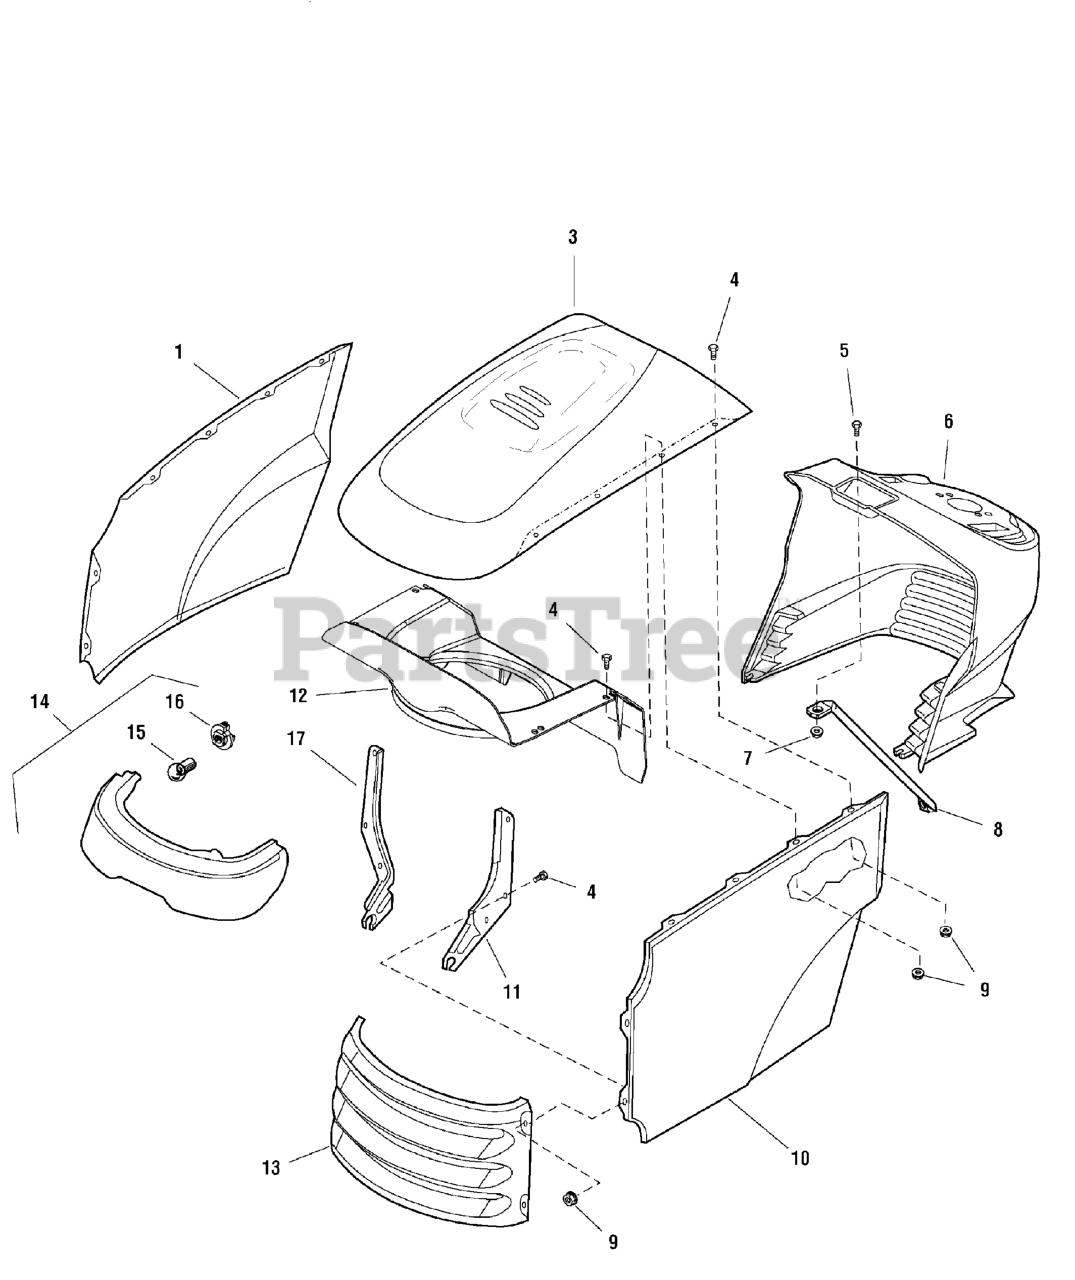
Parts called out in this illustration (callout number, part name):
1	PANEL, RH Side
3	HOOD, with Louvers
4	CAPSCREW, Hex Head Flange Lock,1/4-20 x 5/8
5	SCREW, Pan Head Phillips, #10-24 x 1
6	DASHBOARD, RMO, Black
7	NUT, Hex Nylock,#10-24
8	ROD, Dash Support
9	NUT, Hex Flange Lock, 1/4-20
10	PANEL, LH Side
11	HINGE, LH
12	DUCT, Air Inlet
14	HEADLIGHT ASSEMBLY
15	BULB, Headlight
16	SOCKET, Headlight
17	HINGE, RH
